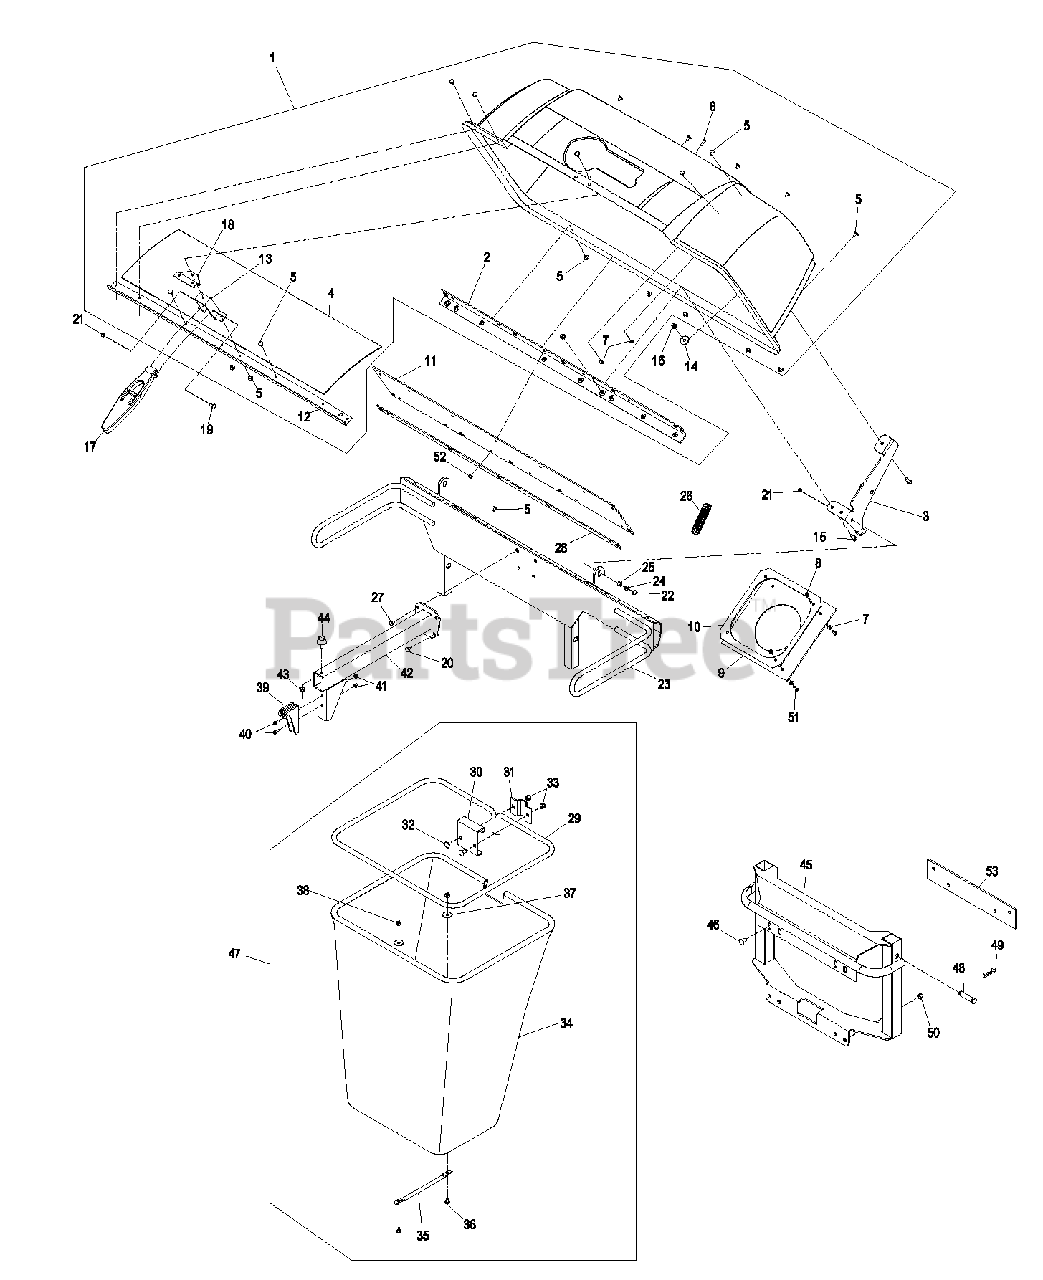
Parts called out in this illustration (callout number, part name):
1	ASM, HOOD
2	STIFFENER-BAGGER, TOP
3	HINGE ASM
4	SCREEN-BAGGER
5	RIVET-BLIND
6	SCREW-HEAD, TRUSS
7	WASHER-FLAT
8	NUT-LOCK, NI
9	SEAL-CHUTE
10	CLAMP-SEAL
12	SUPPORT-SCREEN
13	ANCHOR-LATCH
15	SCREW-HH
18	REINFORCEMENT-LATCH
19	SCREW-HH
20	SCREW-HH
21	NUT-LOCK, NI
22	SCREW-HH
23	BAGGER UPRIGHT ASM
24	WASHER-FLAT
26	SPRING-EXTENSION
27	SCREW-HSBH
28	PLATE-BACKING
29	FRAME-BAG
30	HANGER-BAG
32	BOLT-CARR
33	NUT-LOCK, NI
35	HANDLE-BAG
36	BOLT-CARR
38	NUT-LOCK, NI
40	SCREW-PPH
42	SUPPORT-BAG
45	BAGGER MOUNT ASM
46	SCREW-HH
48	PIN-CLEVIS
49	PIN-COTTER
51	SCREW-PPH
52	NUT-LOCK, SIDE
53	SPACER,COUNTERWEIGH
